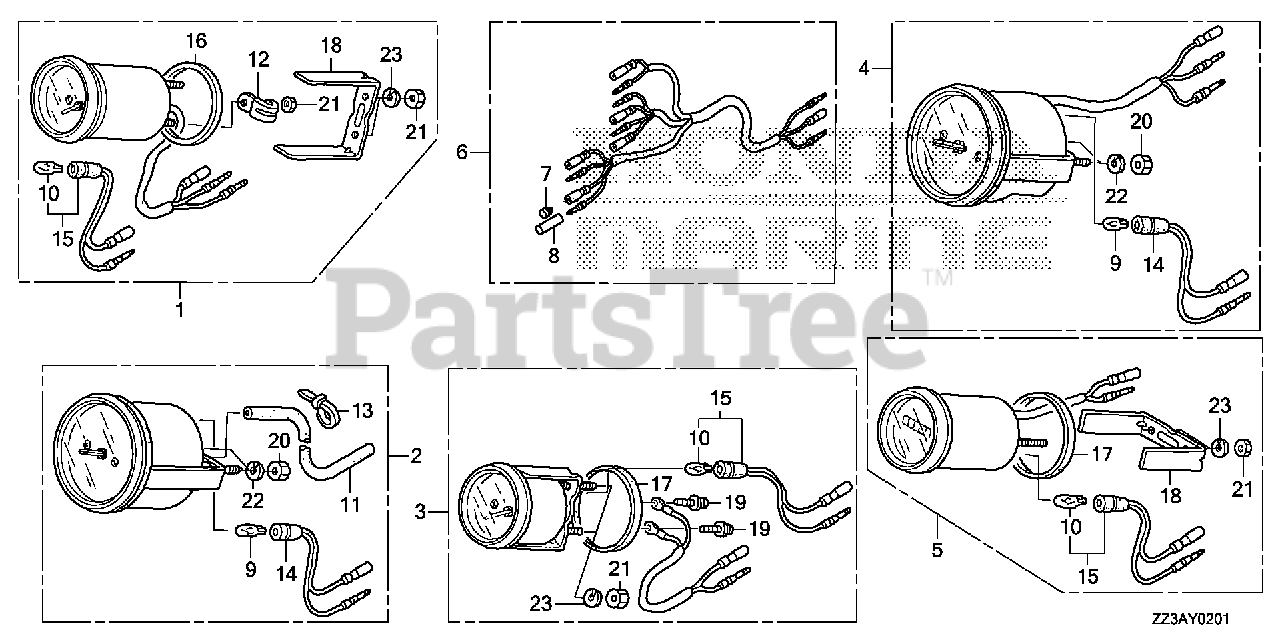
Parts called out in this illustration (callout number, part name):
1	METER KIT, TRIM
1	METER KIT, TRIM (B)
2	SPEEDOMETER KIT
2	SPEEDOMETER KIT (B)
3	METER KIT, VOLT
3	METER KIT, VOLT (B)
4	METER KIT, TACHO
4	METER KIT, TACHO (B)
5	METER KIT, HOUR (NA USE ALT:39700-ZW5-000ZA)
5	METER KIT, HOUR (B) (NA USE ALT:39700-ZW5-000ZA)
6	HARNESS ASSY., METER (B)
7	PLUG, CONNECTOR (INNER)
8	PLUG, CONNECTOR (OUTER)
9	BULB, WEDGE BASE (T10) (12V 1.7W) (STANLEY)
10	BULB, WEDGE BASE (12V 1.7W)
11	TUBE, SPEED METER (4X7X8000)
12	CLAMP
13	BAND, SELF-LOCK
14	SOCKET
15	SOCKET
16	GASKET
17	GASKET
18	BRACKET
19	SCREW-WASHER (3X22)
20	NUT, HEX. (5MM)
21	NUT, HEX. (4MM)
22	WASHER, SPRING (5MM)
23	WASHER, SPRING (4MM)
